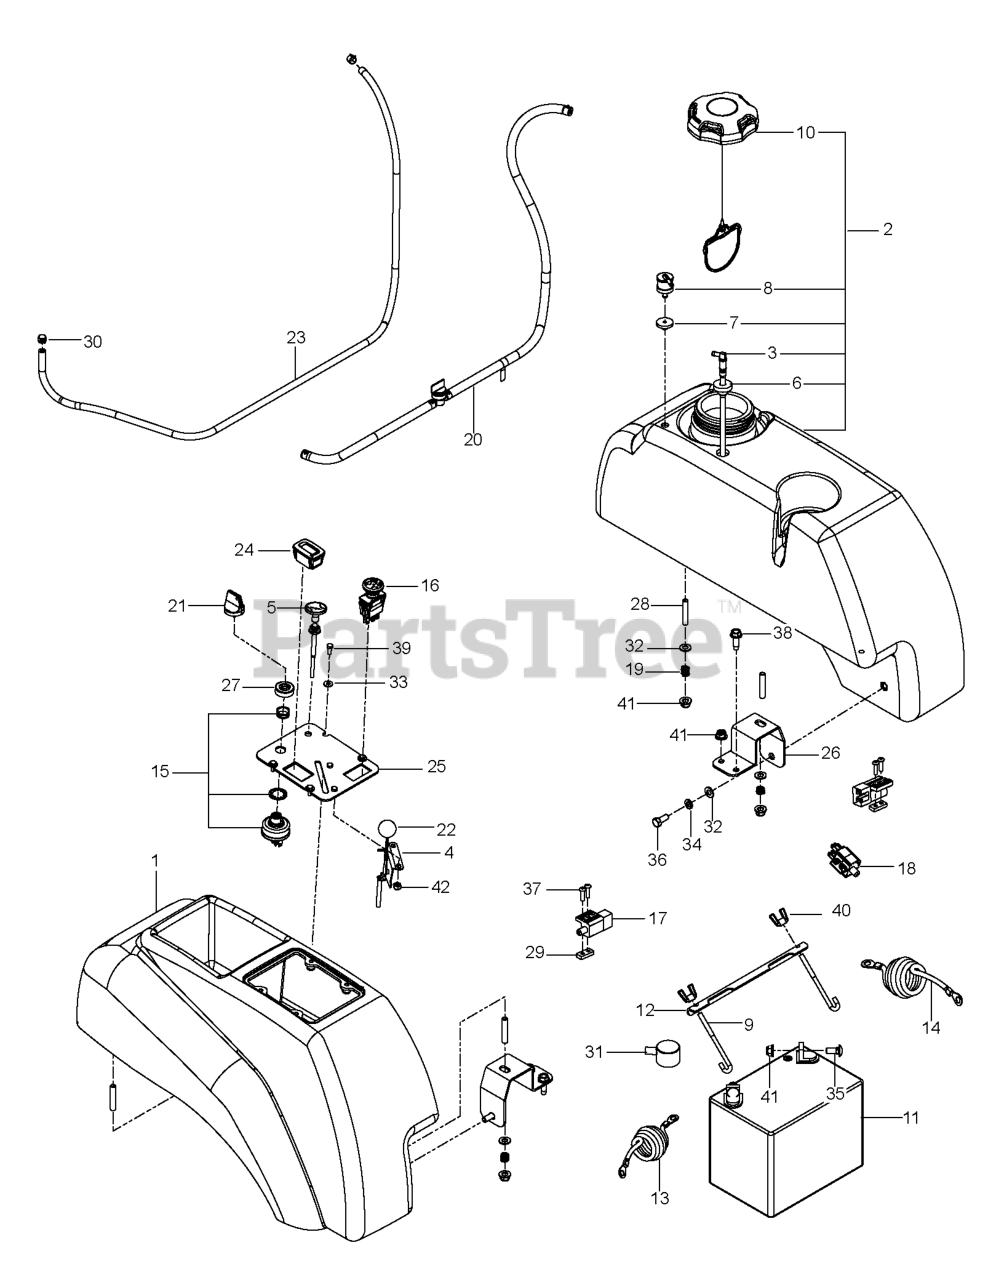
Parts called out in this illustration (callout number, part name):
1	FENDER CONSOLE
2	FUEL.TANK.ASSY.LH.MZ.GRY
3	FITTING, FUEL
4	THROTTLE CONTROL W/BALL KNOB
5	CABLE, CHOKE
6	RUBBER GROMMET
7	GROMMET, CHECK VALVE
8	VALVE.FUEL.CHECK
9	HOOK, "J"
10	CAP, FUEL
11	BATTERY, 12 V 330 AMP
12	BRACKET, BATTERY MOUNT
13	CABLE.BATT.SOLENOID.MZ.RED.25"
14	CABLE.GROUND.BATT.MZ.BLACK.39"
15	SWITCH, IGNITION, INDAK
16	RP SWITCH.PTO.TERMINAL.STD.RED
17	SWITCH INTERLOCKT
18	SWITCH.INTRLCK.CLUTCH.
20	FUEL.HOSE.SHUT.OFF.ASM.10".26"
21	KEY, IGNITION
22	KNOB.ROUND.BALL.BLACK
23	HOSE.3/16".VAPOR.LINE.64"LGTH
24	GUAGE.SRVCMNDR.HRMTR.
25	PLATE.CONSOLE.BLACK
26	SUPPORT, TANK, BLK
27	CAP IGNITION NUT
28	STUD, 5/16C
29	PLATE NUT ZTR
30	CLAMP, HOSE
31	COVER.TERMINAL.BATTERY
32	WASHER
34	WASH.5/16.SLW.ZD
35	RP BOLT 5/16-18 X3/4 ZN/YEL GR
36	BOLT.FIN.HEX.5/16-18X3/4
37	SCR #10-24 X .75 SKT HD BLK
38	SCREW
39	HCS #10-24 X 1/2
40	WING NUT 1/4
41	5/16-18 NYLOC FLANGE NUT
42	NUT 10-24 NYLOC
